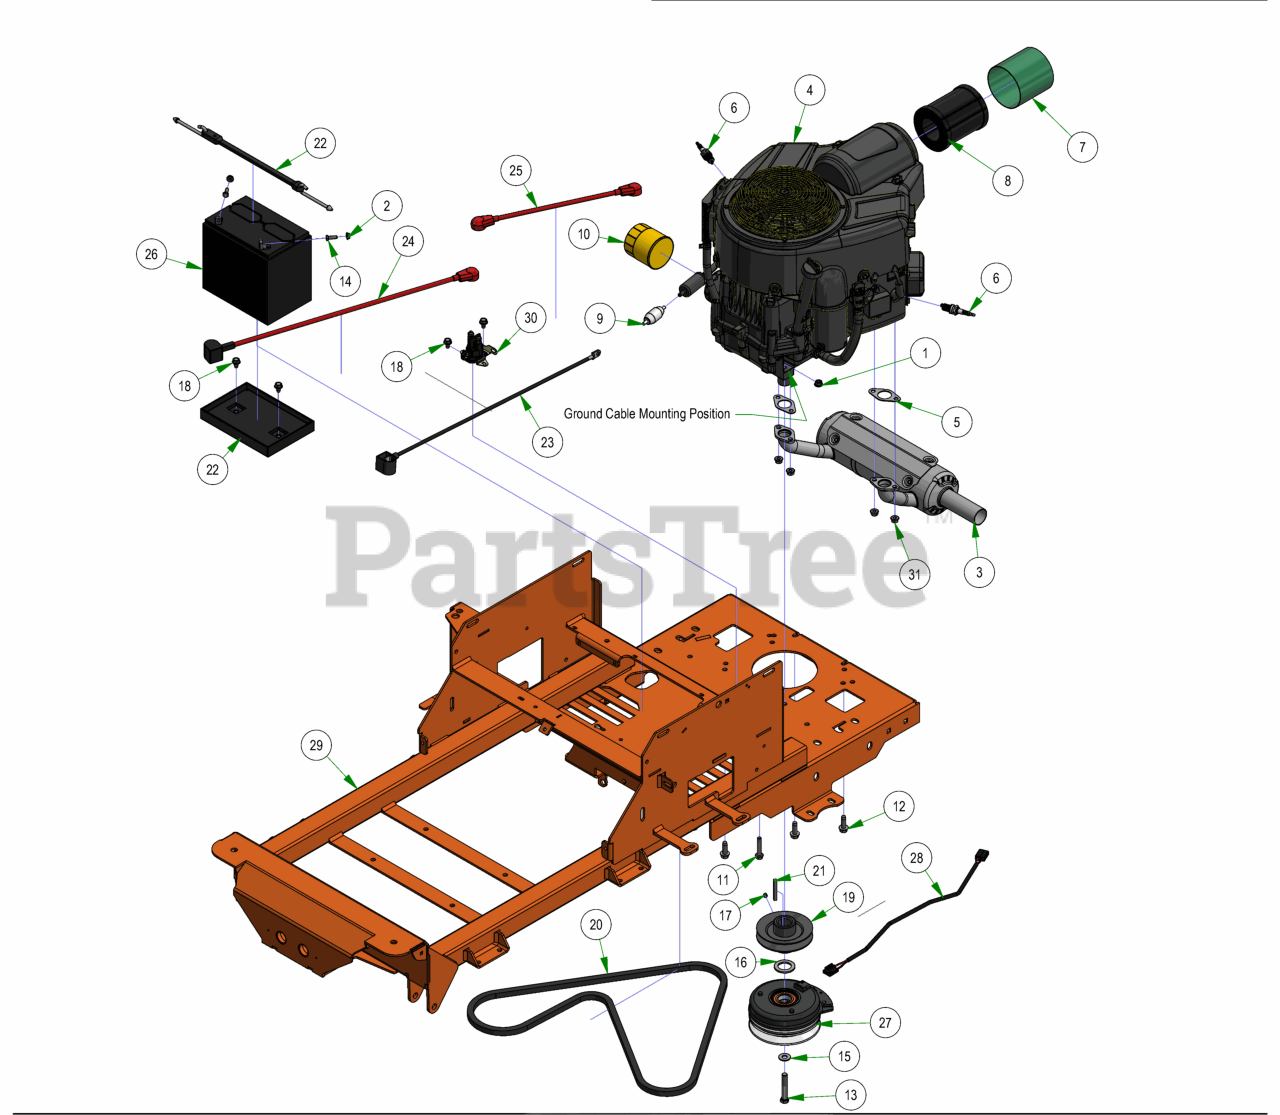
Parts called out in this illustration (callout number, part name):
1	5/16-18 Gr5 Distorted-Thread Flange Locknut
2	1/4-20 HEX SERRATED FLANGE NUT HARD/ZINC
3	2017 Compact Outlaw Exhaust 810 Vanguard
4	Vanguard 27hp CXI with Out Oil Filter Maverick
5	Exhaust Gasket
6	Spark Plug
7	pre-Cleaner for Vanguard CXI Engine
8	Air Filter for Vanguard CXI Engine
9	Universal Inline Fuel Filter
10	Oil Filter
11	5/16-18x1-3/4 Gr5 Hex Flange Screw Zinc Clear
12	3/8-16 X 1-1/8 HEX WASHER UNSLOT SERRATED (TRI-LOB) TRS ZINC YELLOW
13	7/16-20 X 2.5" HEX Bolt GR.8 W/Patch
14	1/4-20 X 3/4 HEX CAP SCREW (GR.5) ZINC
15	3/8 FLAT WASHER USS (1" OD) ZINC
16	1.140 ID X 1.750 OD X .132 THICK FLAT WASHER PLAIN
17	5/16-24 X 1/4 SOCKET SET SCREW (CUP PT) PLAIN
18	5/16-18 X 1/2 HWH unslot (F) tcs zinc
19	4 3/4 Motor Pulley
21	1/4 X 2 SQ MACHINERY KEY 1018 STL PLAIN
22	2023 Battery Hold Down Assembly
23	24 inch Black Cable – MZ/ZT
24	24" Red Battery Cable
25	14" Red Battery Cable
26	SP-35 Battery
27	120 Ft Lb. Clutch - 1 1/8" Shaft
28	Clutch Pigtail
29	2025 ZT Elite Frame
31	Muffler Nut for 015-0511-00 Briggs
